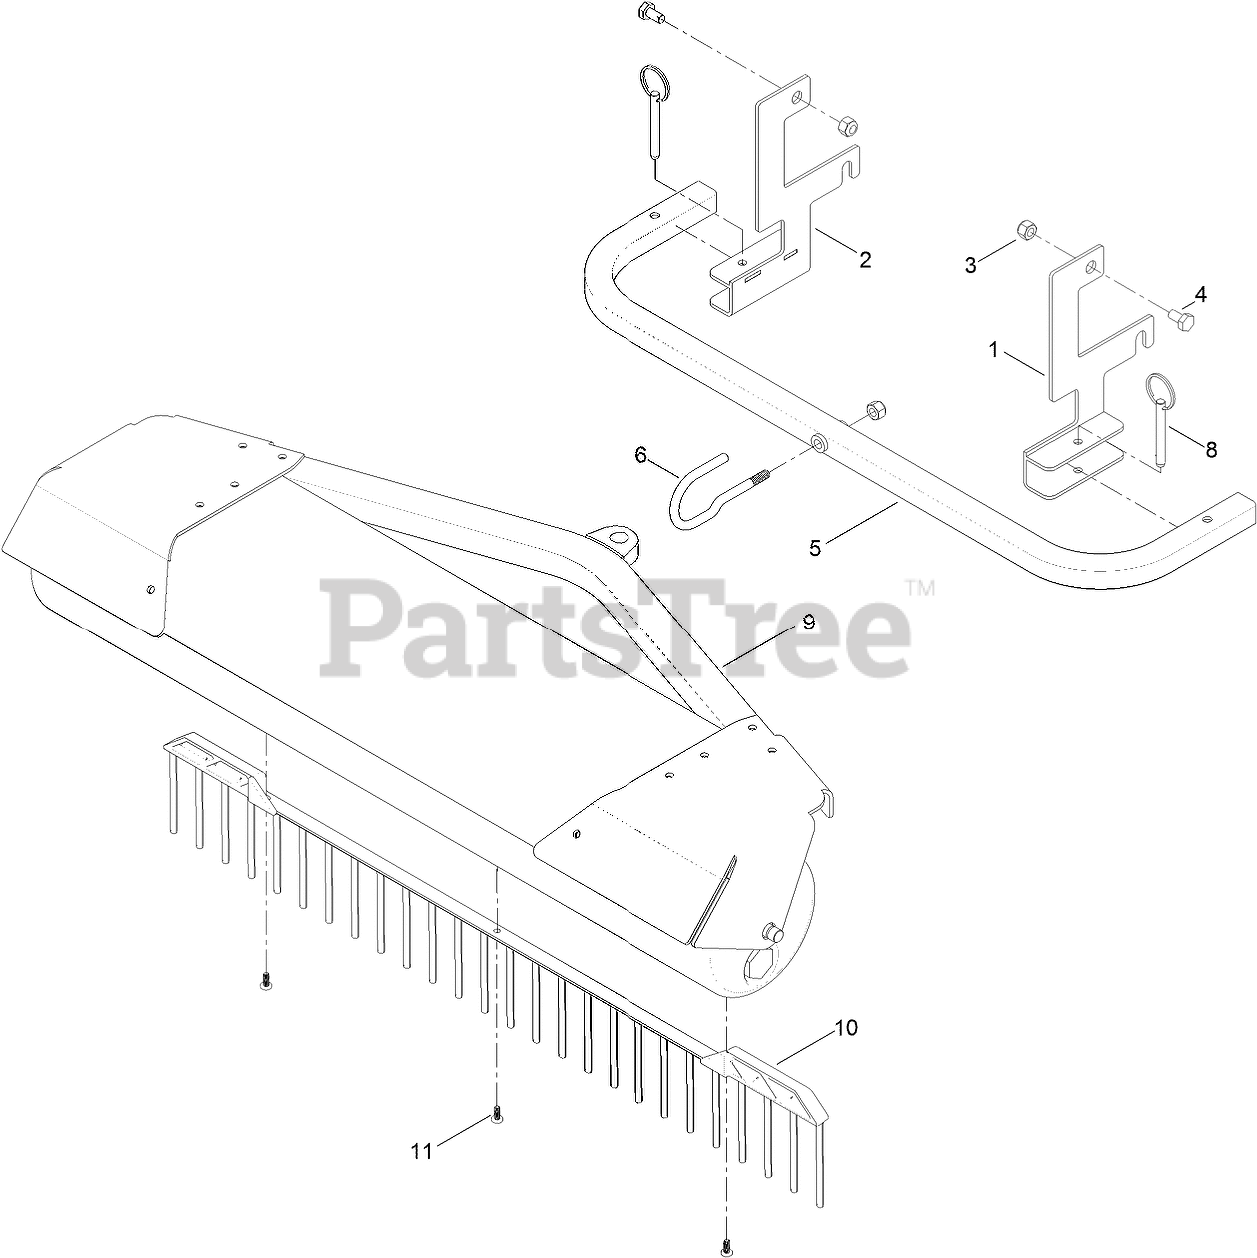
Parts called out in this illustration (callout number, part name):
1	MOUNT-RH
2	MOUNT-LH
3	NUT-LOCK, NI
4	SCREW-HH
8	PIN-SPRING
9	TRAILER-STRIPER, LAWN
11	SCREW-PPH
